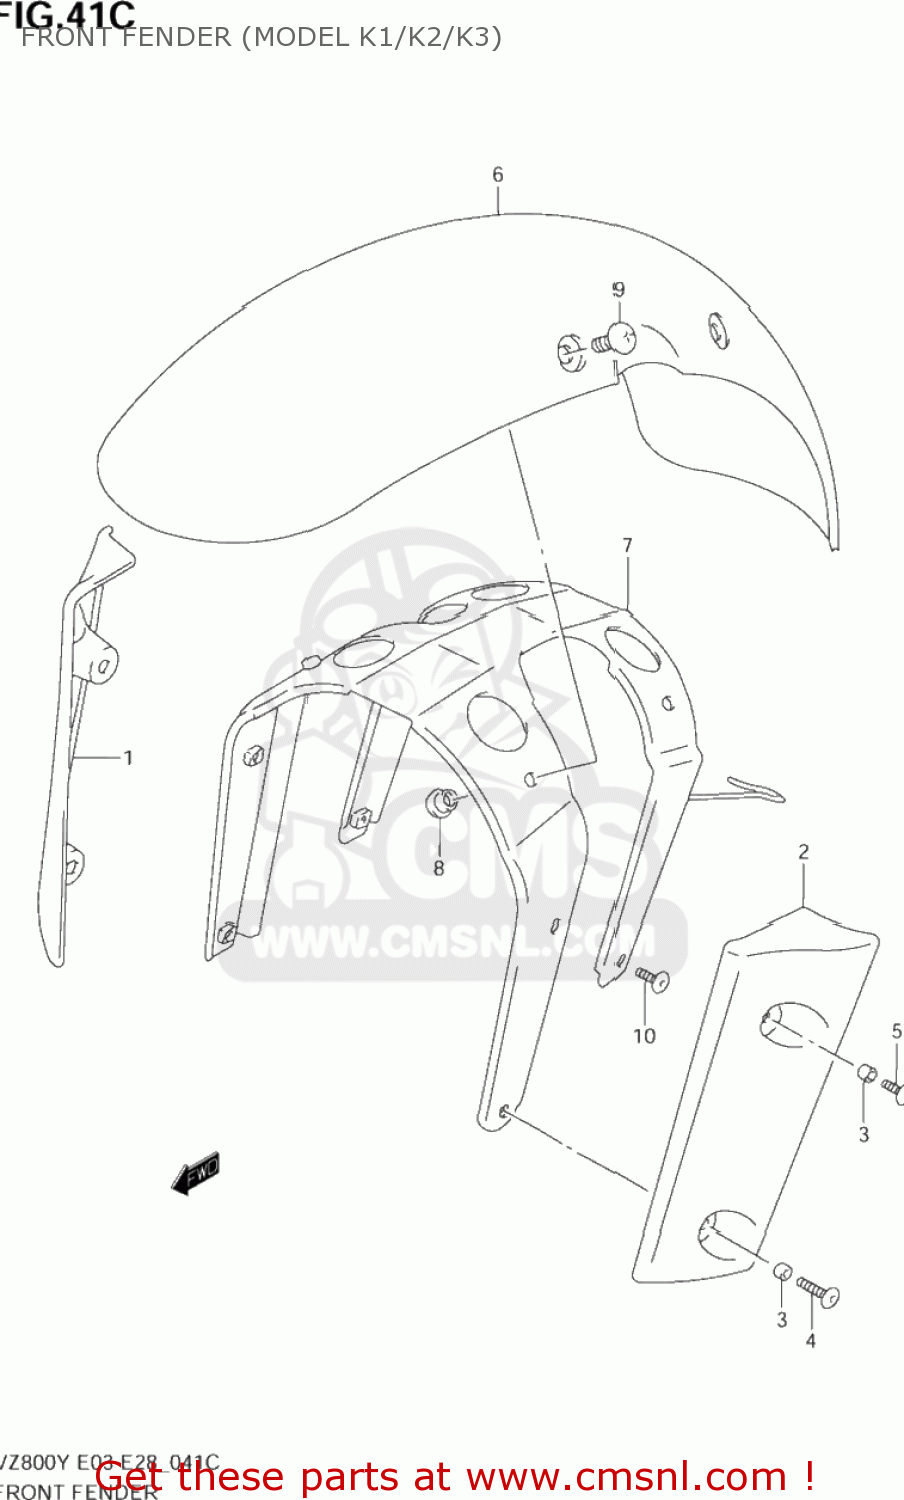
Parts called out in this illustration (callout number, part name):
1	COVER,FR FORK SIDE,R
2	COVER,FR FORK SIDE,L
3	SPACER(6.1X8X3.5)
4	SCREW(6X20)
5	SCREW(6X12)
6	FENDER,FR
7	BRACE,FR FENDER
8	NUT
9	SCREW(6X12)
10	SCREW(6X16)
